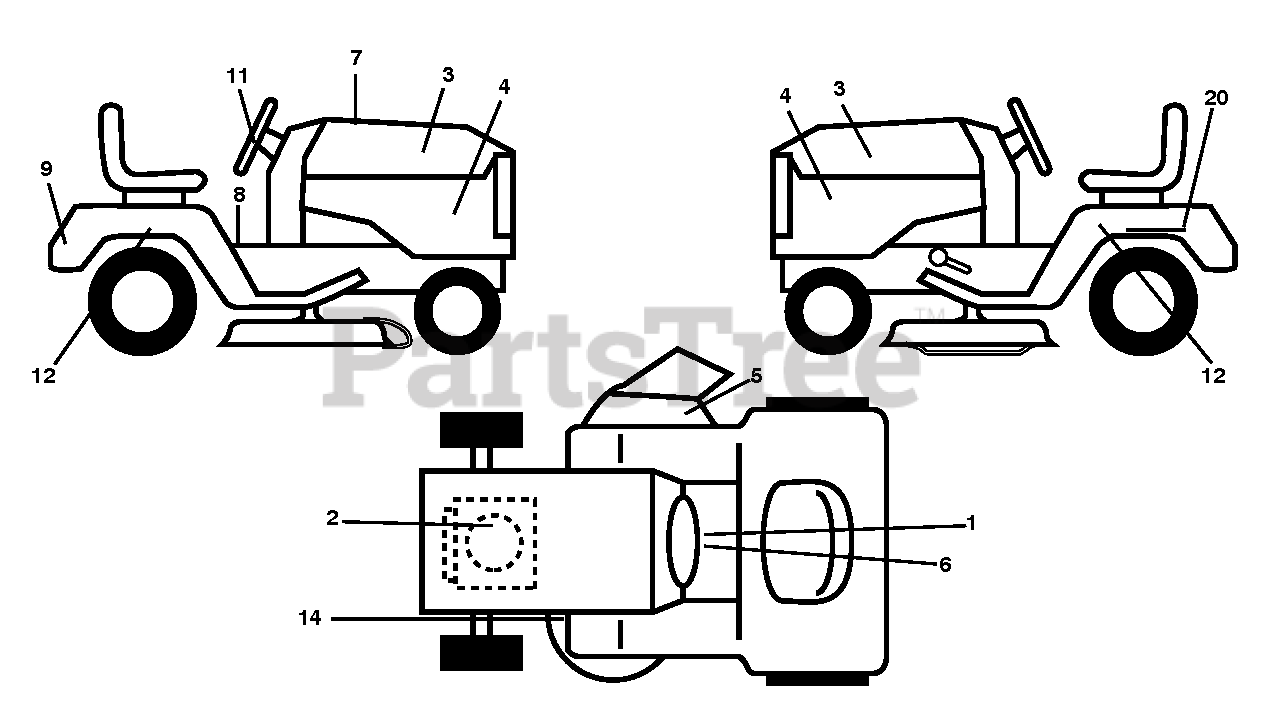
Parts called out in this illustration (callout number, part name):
1	DECAL, WARNING SPARK ARRESTOR
2	DECAL.ENGINE.B&S.(278443)
5	DECAL.WARN.KEEP.HAND.AWAY
8	Fender Warning Decal, English
11	DECAL.STEER.WHEEL.POULAN.PRO
14	DECAL V BELT SCHEMATIC
20	DECAL BTRY SYMBOLS
